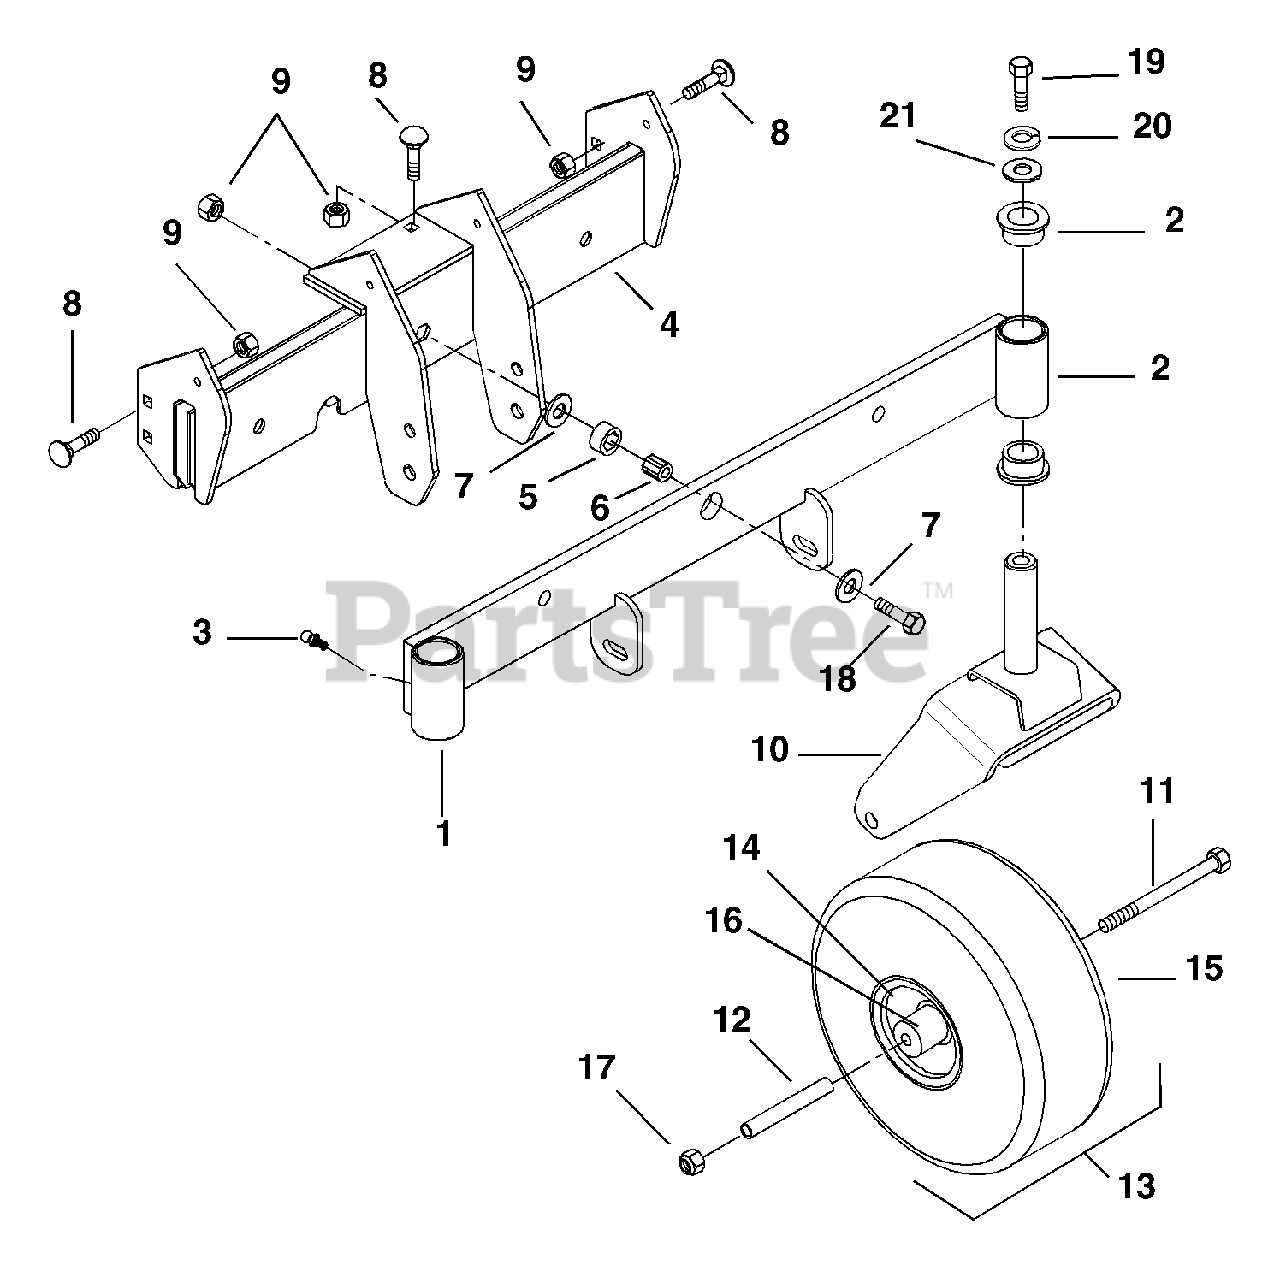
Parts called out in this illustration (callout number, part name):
1	Axle Weldment
2	Bushing-Flange 1.020 x 1.385 x .75 x 1.75
3	Fitting-Lube .25-28 x .256
4	Axle Frame Weldment (42" Decks)
4	Axle Frame Weldment (48" Decks)
5	Bushing-Sleeve .626 x 1.000 x .524
6	Bushing-Sleeve .377 x .623 x .775
7	Washer-Flat-Steel .38 x 1.50 x .125
8	Bolt-Round Head Square Neck .38-16 x .75 Grade 5
9	Nut-Locking-Center .375-16
10	Fork-Caster
11	Bolt-Hex .50-13 x 6.50
12	Bushing-Caster Fork
13	Wheel & Tire 11 x 4.00-5 (Includes 14 - 16)
14	Rim Assembly
15	Tire
16	Bearing
17	Nut-Locking-Center .50-13 Grade 5
18	Bolt-Hex .38-16 x 1.75 Grade 5
19	Bolt-Hex .38-16 x 1.25 Grade 5
20	Washer-Lock 038 x .094
21	Washer-Flat-Steel .38 x 1.50 x .125
